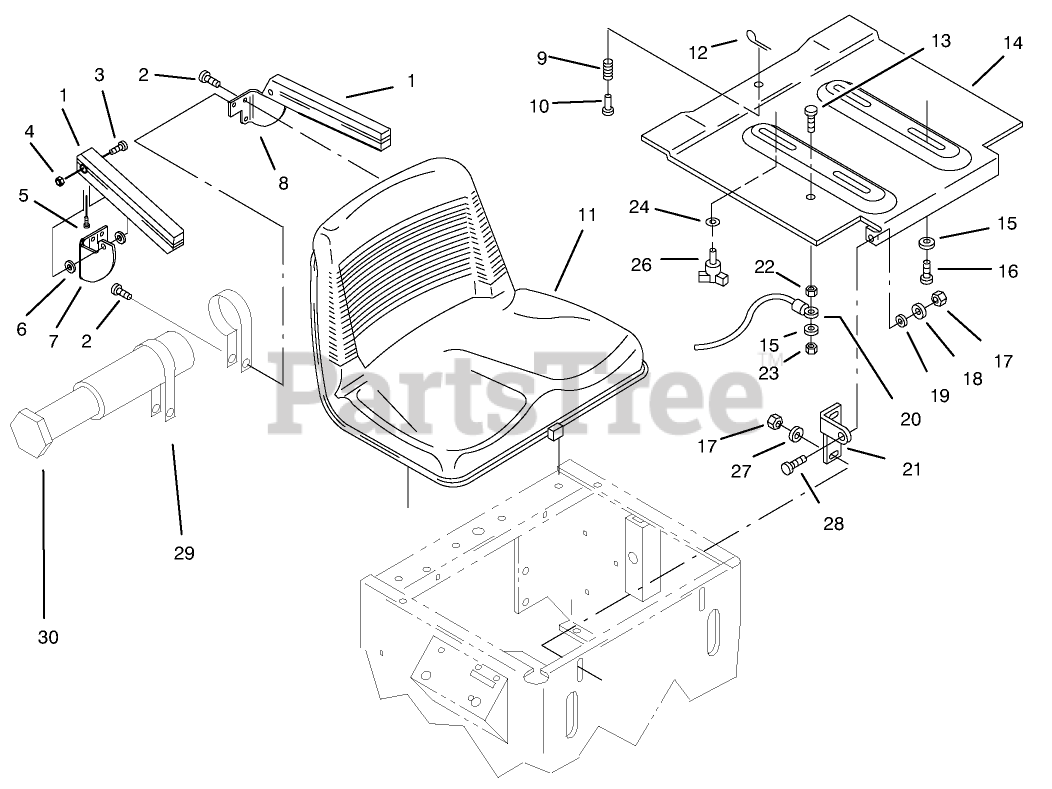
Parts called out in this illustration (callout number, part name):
1	ARMREST
2	3/8-16 X 5/8 SCREW
3	3/8-16X1-1/2 SCREW
4	3/8-16 ACORN LOCKNUT
5	3/8-16 X 3/4 SCREW
6	NYLON SPACER
7	RH ARM BRACKET
8	LH ARM BRACKET
9	SPRING-COMPRESSION
11	Seat 620-Z (Incl. Ref.#1-8)
12	PIN-COTTER
13	SCREW-HH
14	PLATE SEAT PIVOT R
15	WASHER-FLAT
16	BOLT 5/16-18X5/8
17	NUT-LOCK, NI
18	WASHER-FLAT
19	SPACER
20	Cable
21	Seat Pivot Bracket RH
22	NUT-HEX
23	NUT-LOCK, NI
24	LOCKWASHER INT EXT
27	WASHER-FLAT
28	BOLT-CARR
29	CLAMP-R
30	TUBE-MANUAL
